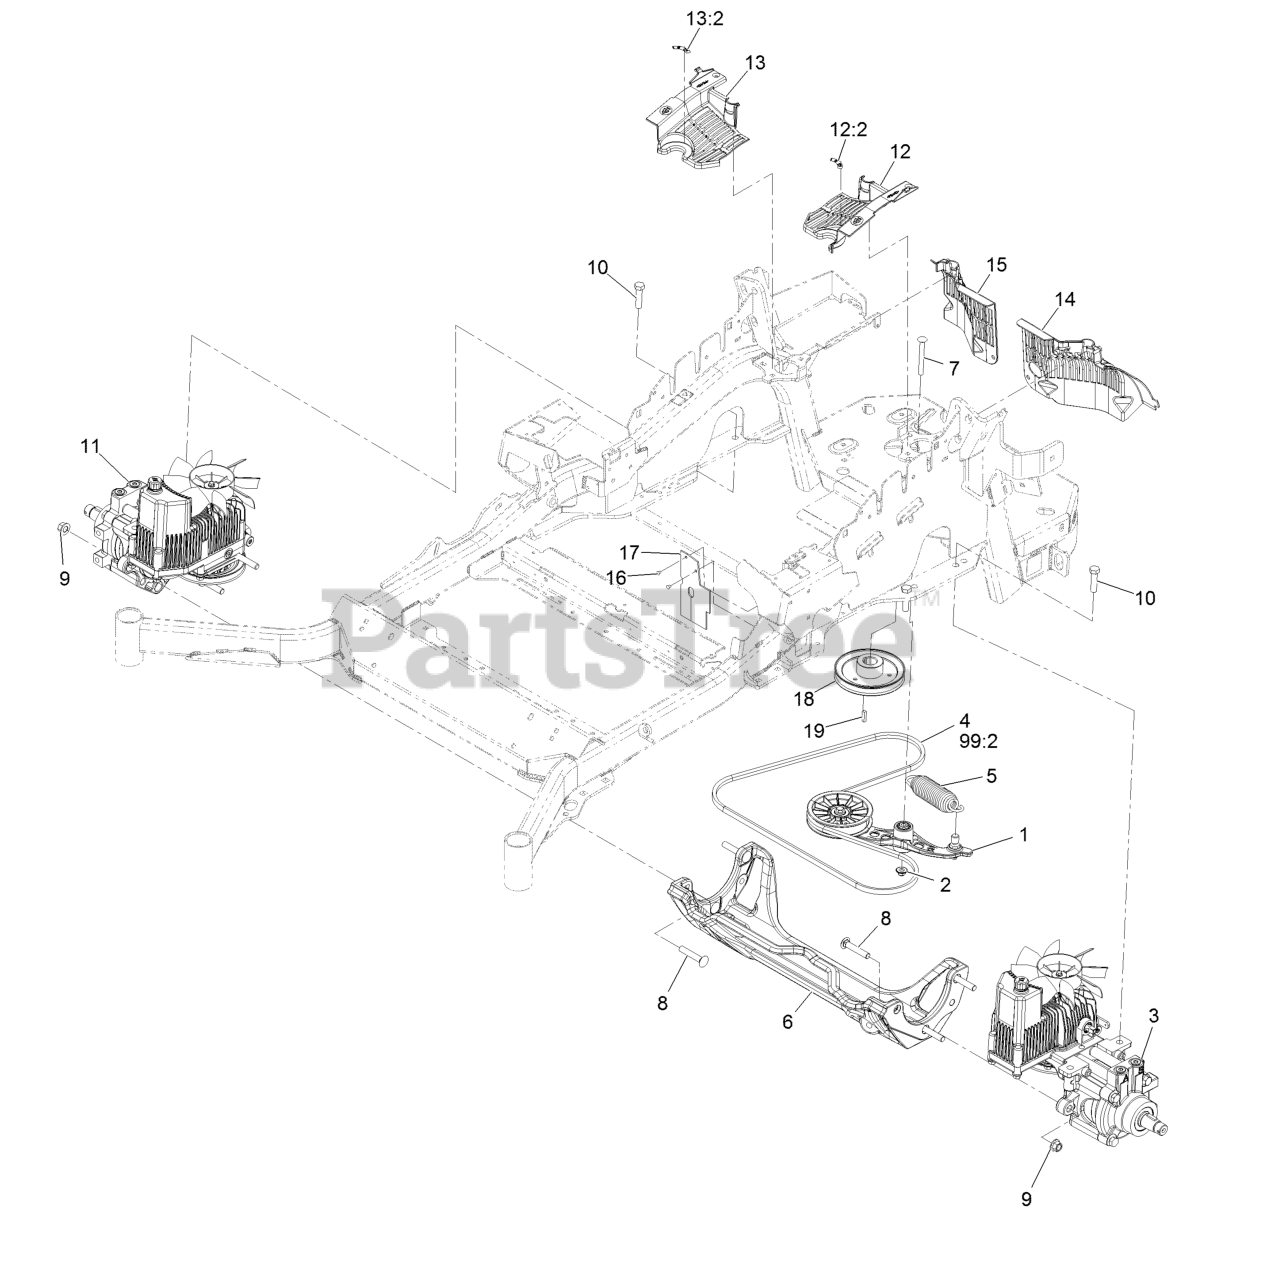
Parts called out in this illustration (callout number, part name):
1	Pump Idler ASM
2	Nut-Nyloc 3/8-16 Flg
3	LH Hydro ASM (16Cc W/Shock)
4	Belt
5	Spring-Extension
6	Cradle-Hydro
7	Bolt-Carriage Shoulder 3/8-16 X 3 1/2
8	Screw-CARR
9	Nut-Lock 1/2-13
10	Screw-HH 1/2-13 X 1 1/4
11	RH Hydro ASM (16Cc W/Shock)
12	LH Hydro Guard ASM
12:2	Decal-Oil, Hydro
13	RH Hydro Guard ASM
13:2	Decal-Oil, Hydro
14	Guard-Hydro, Rear (LH)
15	Guard-Hydro, Rear (RH)
16	Rivet 3/16 X 1/4
17	Deflector-Air Flow
18	Sheave
19	Key-Machine 1/4 X 1/4 X 1
99	Bottle-Oil, 32Oz Hydraulic
99	Filter-Hydro
99	Bottle,Oil 1 Gallon Hydraulic
99	Kit, Hydro Service
99:1	Bottle-Oil, 32Oz Hydraulic
99:2	Belt
99:3	Filter-Hydro
